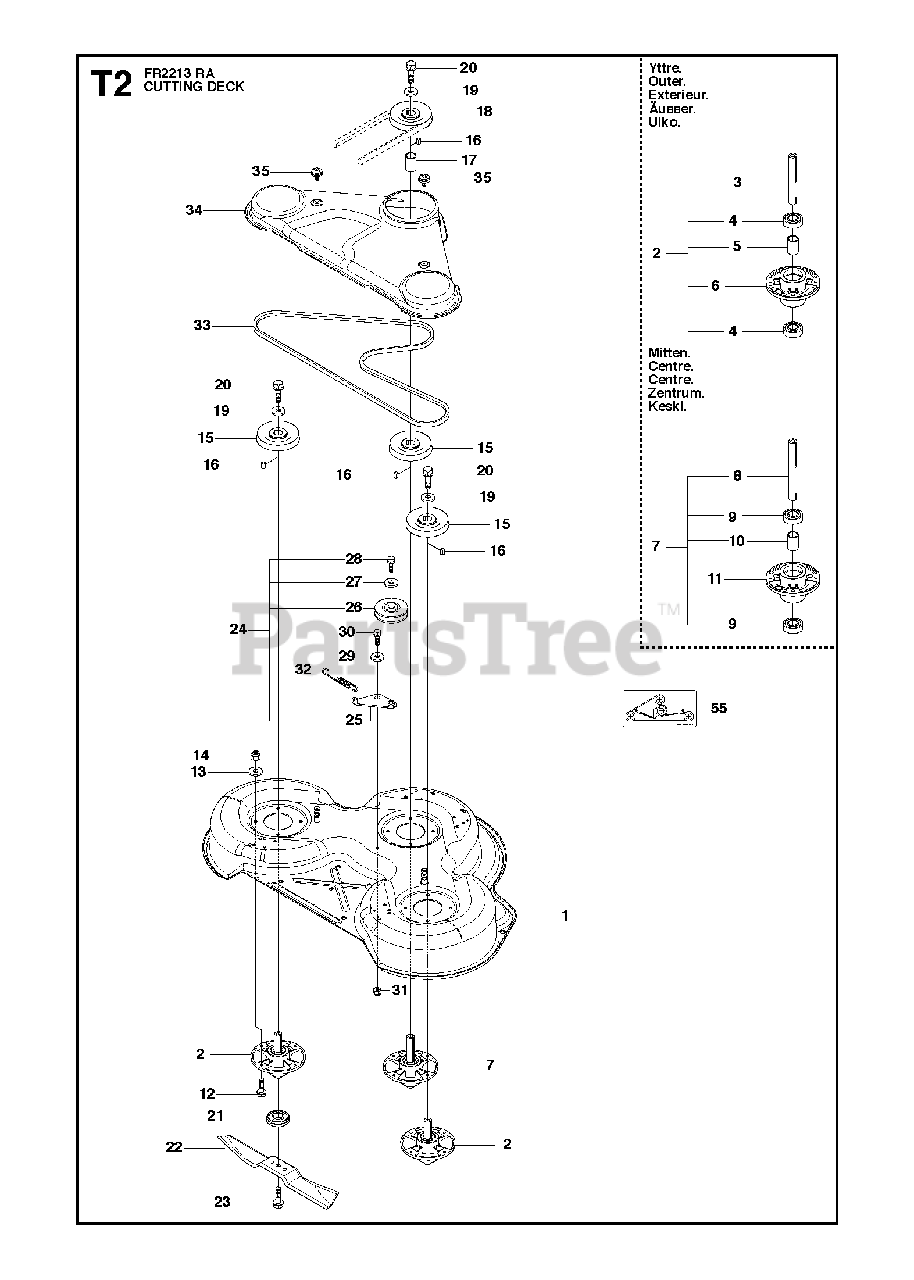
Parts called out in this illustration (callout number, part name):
2	RP SPINDLE ASSY
3	SHAFT
4	BEARING
5	SPACER
6	BEARING HOUSING
9	BEARING
10	SPACER
11	BEARING HOUSING
13	WASHER BRB 8.4X17
14	LOCKNUT M8
25	BRACKET
26	PULLEY
27	SPACER
28	BOLT
29	WASHER
31	LOCKNUT M8
